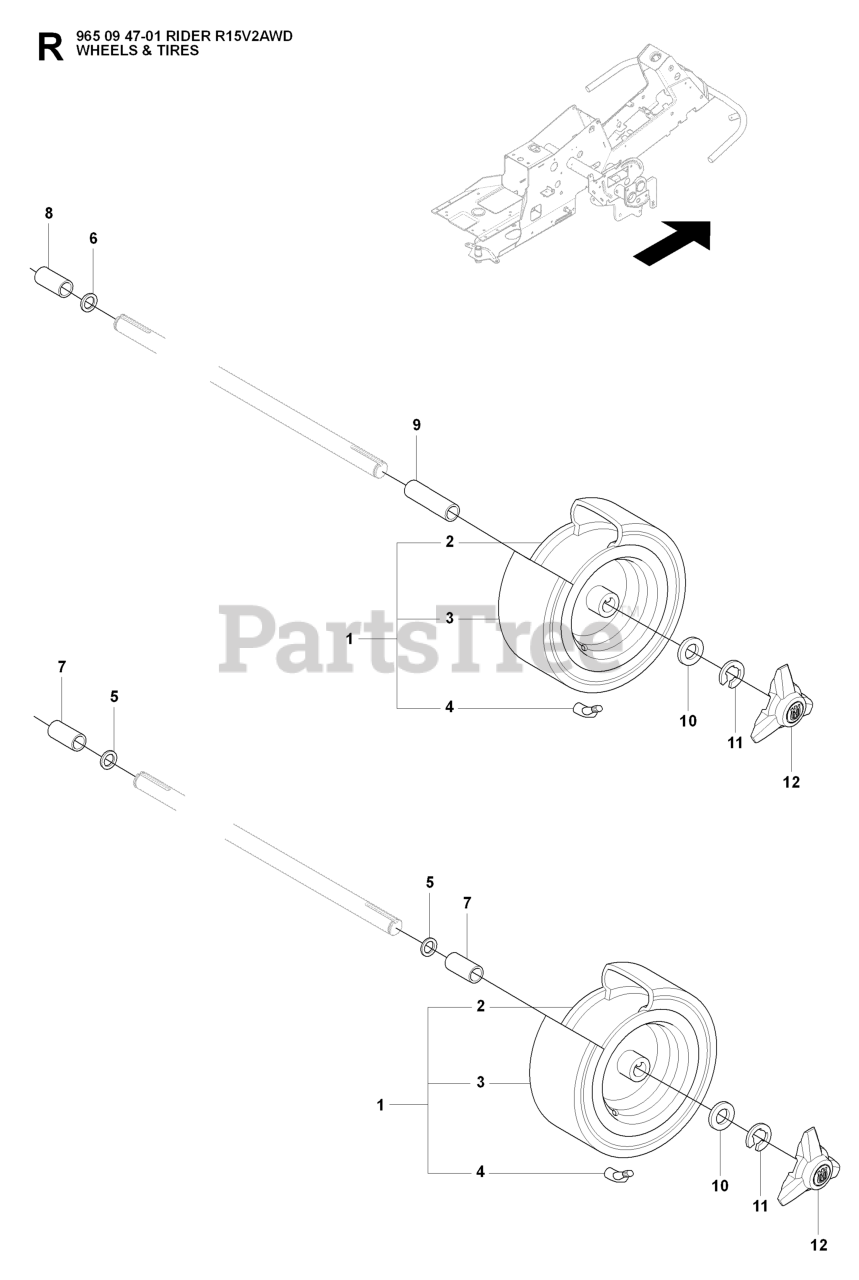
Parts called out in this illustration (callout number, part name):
1	WHEEL
2	RP RIM
7	SPACE SLEEVE
11	RETAINING RING
